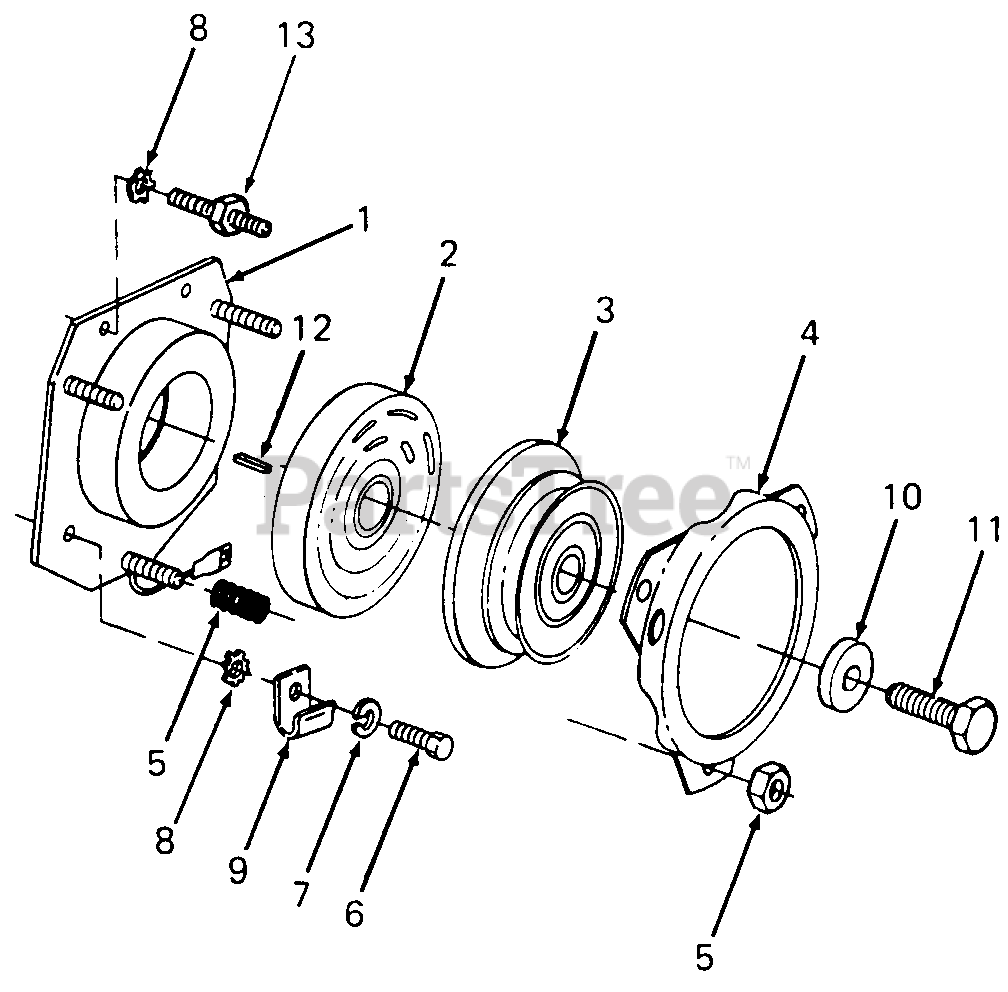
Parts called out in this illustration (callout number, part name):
2	Rotor (Model 1872)
3	Armature (Model 1872)
4	Drum, Brake
5	Spring & Nut Kit
6	Screw, Hex Cap, 7/16-14 X .75 Lg GR5
7	Washer, Lock, 7/16
8	Washer, Ext. Lock, .45 X .75 X .035 Thk
9	Clamp, Cable
10	Washer, Flat, .47 X 1.5 X .225 Thk
11	Screw, Hex Cap, 7/16-20 X 1.25 Lg GR5
12	Key, Square, 1/4 X .75 Lg
13	Stud, 7/16-14 Trd
